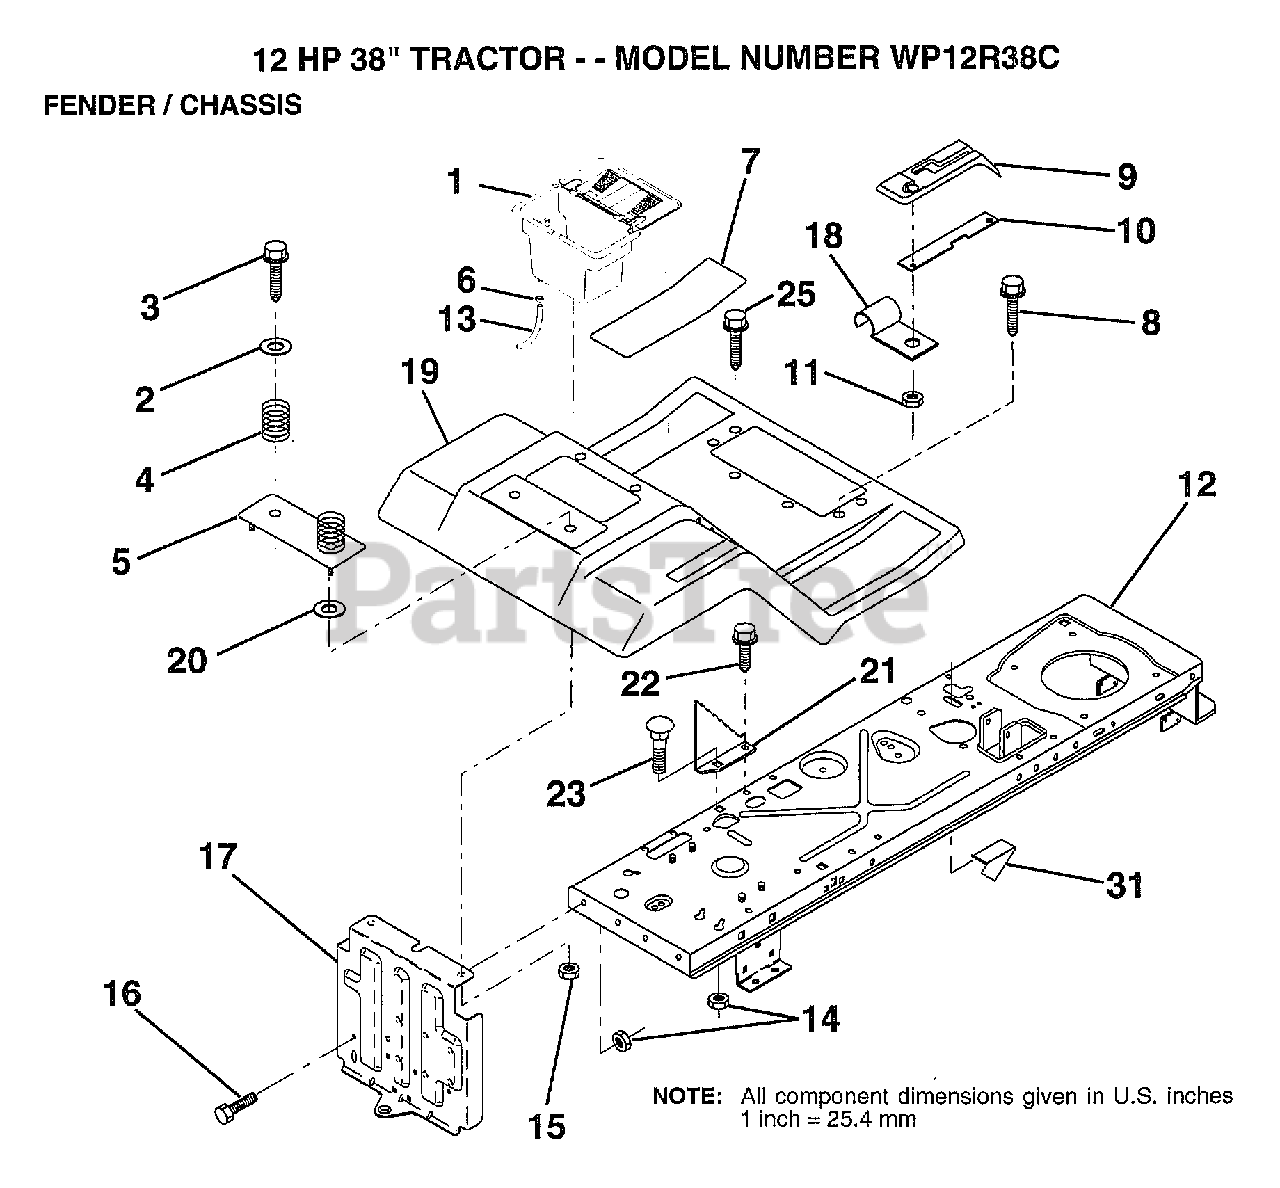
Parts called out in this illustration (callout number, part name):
2	WASHER
3	SCREW
4	SPRING COMPRESSIO
5	BTRY FENDER PLATE
6	HOSE CLAMP T
7	PAD FOOTREST
8	SCREW
10	PLATE LOCK SHIFT
11	NUT
13	TUBE T
14	NUT
15	NUT
16	BOLT
17	DRAWBAR ASM LR
18	"CLIP,INSULATOR"
19	FENDER/FOOT MS505
21	BRACKET STOP DEPT
22	SCREW LT
25	SCREW TI
